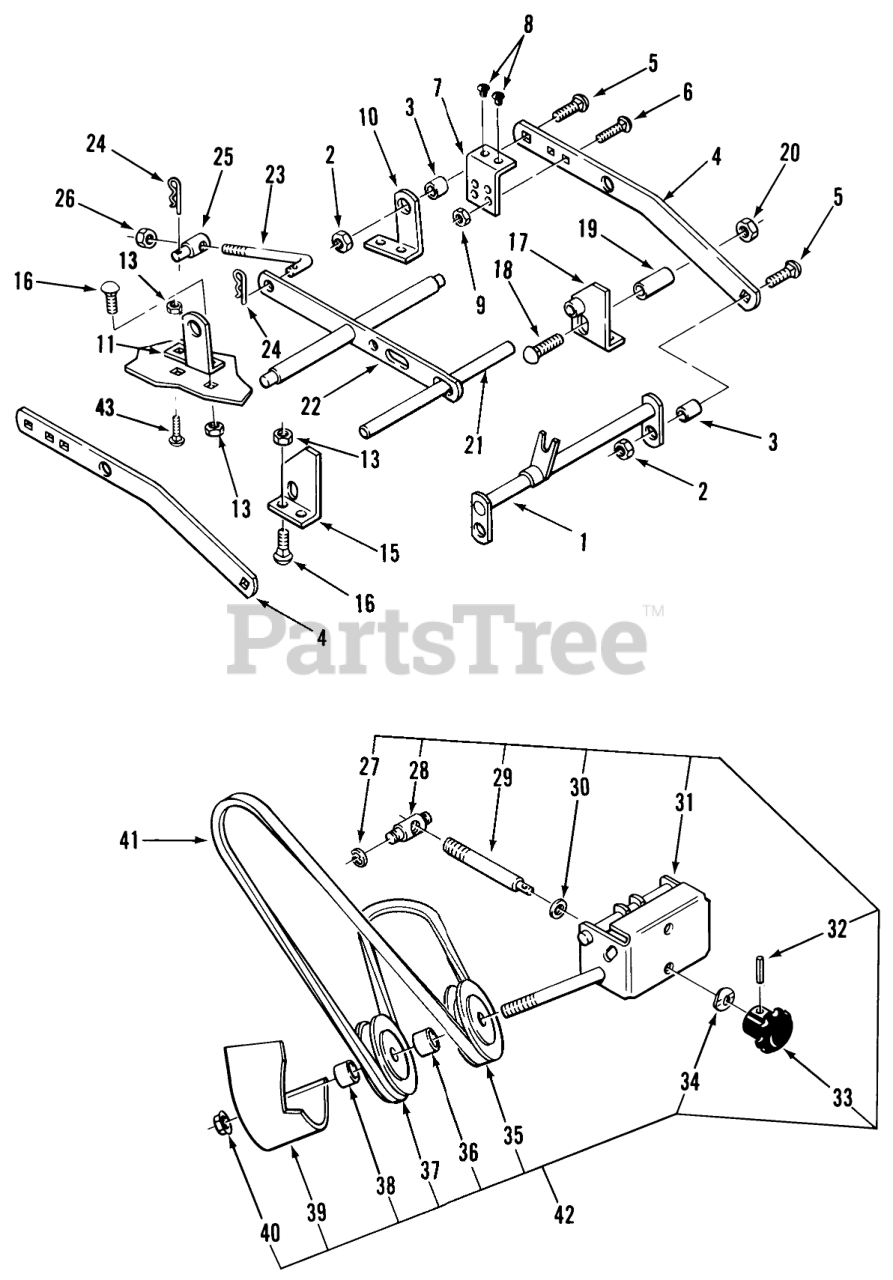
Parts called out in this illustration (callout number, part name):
1	Hitch
2	LOCKNUT-FLANGE
3	SPACER
4	Bar Draft
5	Bolt
6	Bolt-Carriage
7	Bumper-Metal
8	BUMPER-RUBBER
9	Nut
10	LH Rear Bracket
11	Rear Bracket RH
13	Nut
15	Front Bracket RH
16	Bolt-Carriage
17	Front Bracket LH
18	CARRIAGE BOLT -4
20	Nut
21	Front Shaft
22	Leveler
23	ROD-LEVEL ADJUST
24	Hairpin
25	TRUNNION-LIFT
26	NUT
27	RING-RETAINING
28	TRUNNION-DOUBLE
29	ROD ADJ
30	Washer
31	Front Support
32	PIN-ROLL
33	KNOB-ADJUSTMENT
34	WASHER-SPRING
35	Pulley-V
36	SPACER
37	PULLEY-FLAT IDLER
38	SPACER-OUTER
39	Belt Cover
40	Nut 3/4-16 MF
41	V-BELT
42	ASM-SUPPORT,IDLER
43	Bolt
